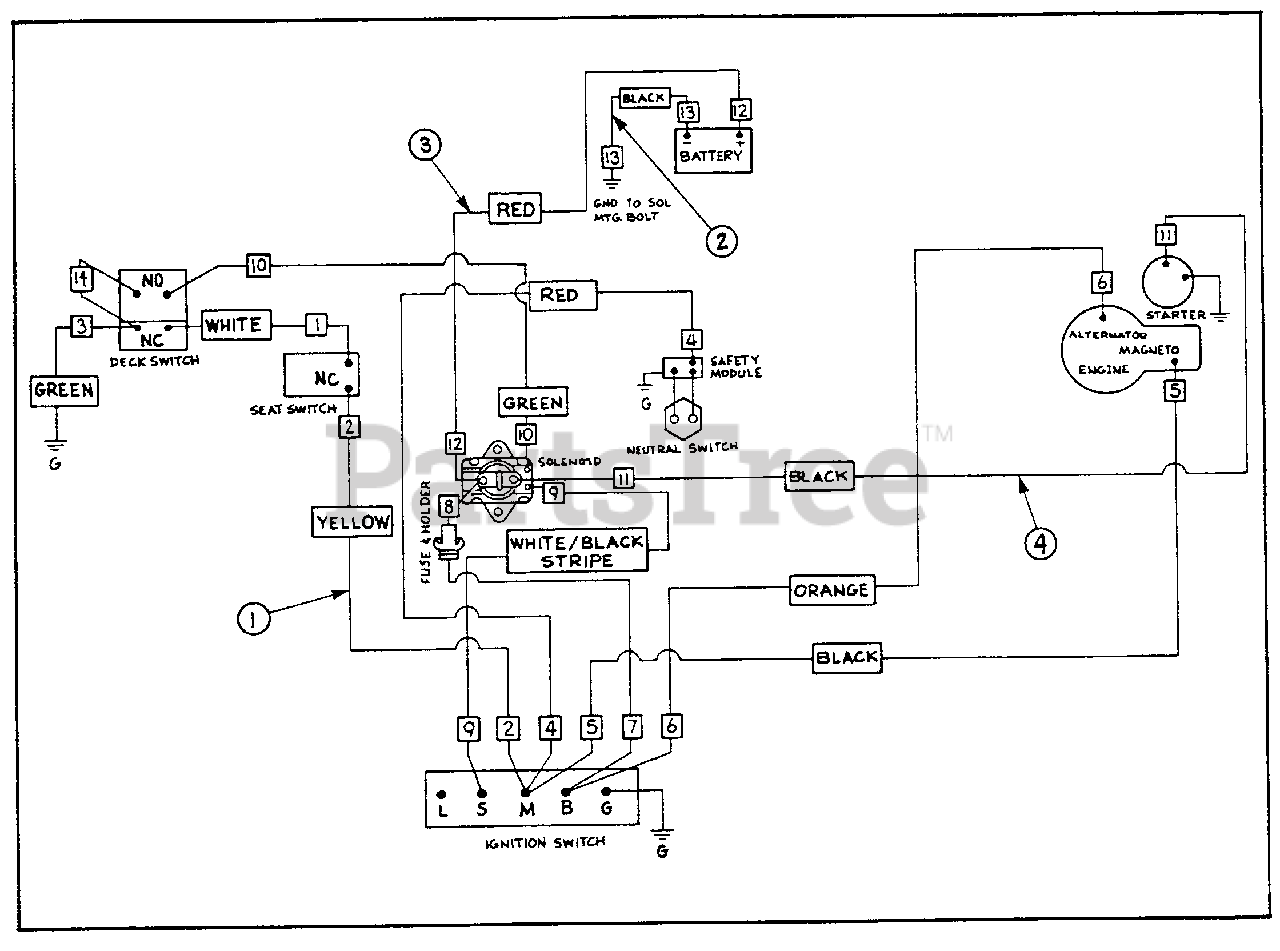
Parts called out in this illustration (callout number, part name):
1	WIRE HARNESS
2	BATTERY CABLE- Ground
3	BATTERY CABLE
4	STARTER CABLE
